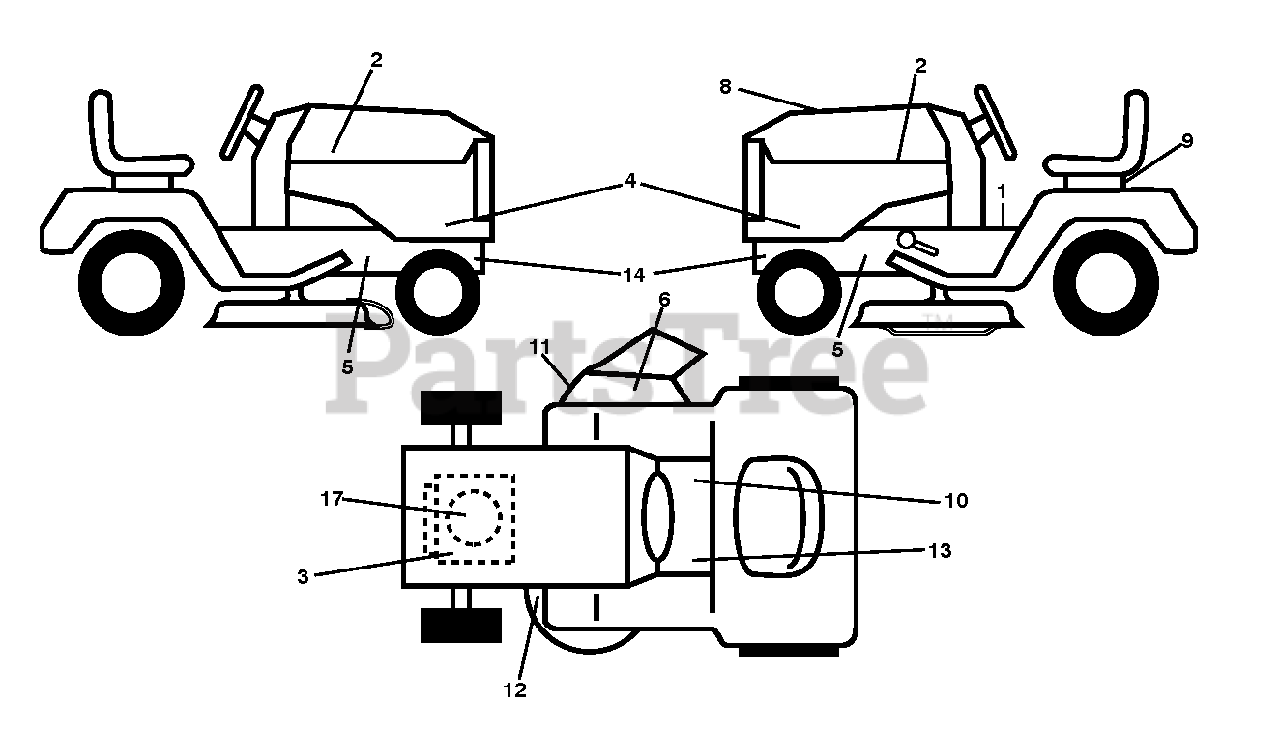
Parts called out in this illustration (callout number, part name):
1	DECAL.READ.OWN.MAN.SYMBOL.LT
2	DECAL.BADGE.170MM.TEXTLOGO.
3	DECAL.ENGINE.WARNING
4	DECAL.SDPNL.HUSQLT.TC130
5	DECAL.CHASSIS.HOT.MUFFLER
6	DECAL, DECK DEFLECTOR, WARNING
8	DECAL DECAL.RPL.BSM21.PB.TLW.3
9	DECAL BTRY SYMBOLS
10	DECAL.PARKING.BRAKE.SADDLE.LT
11	DECAL.WARN.DFLCTR/CTFRG.SRD
12	DECAL.V.BELT.30"
13	DECAL.FNDR.SDLE.BRAKE.CLUTCH.6
14	DECAL.WARNING.SERVCE/FIRE
17	DECAL.ENG.BS.344CC.HS.382271
